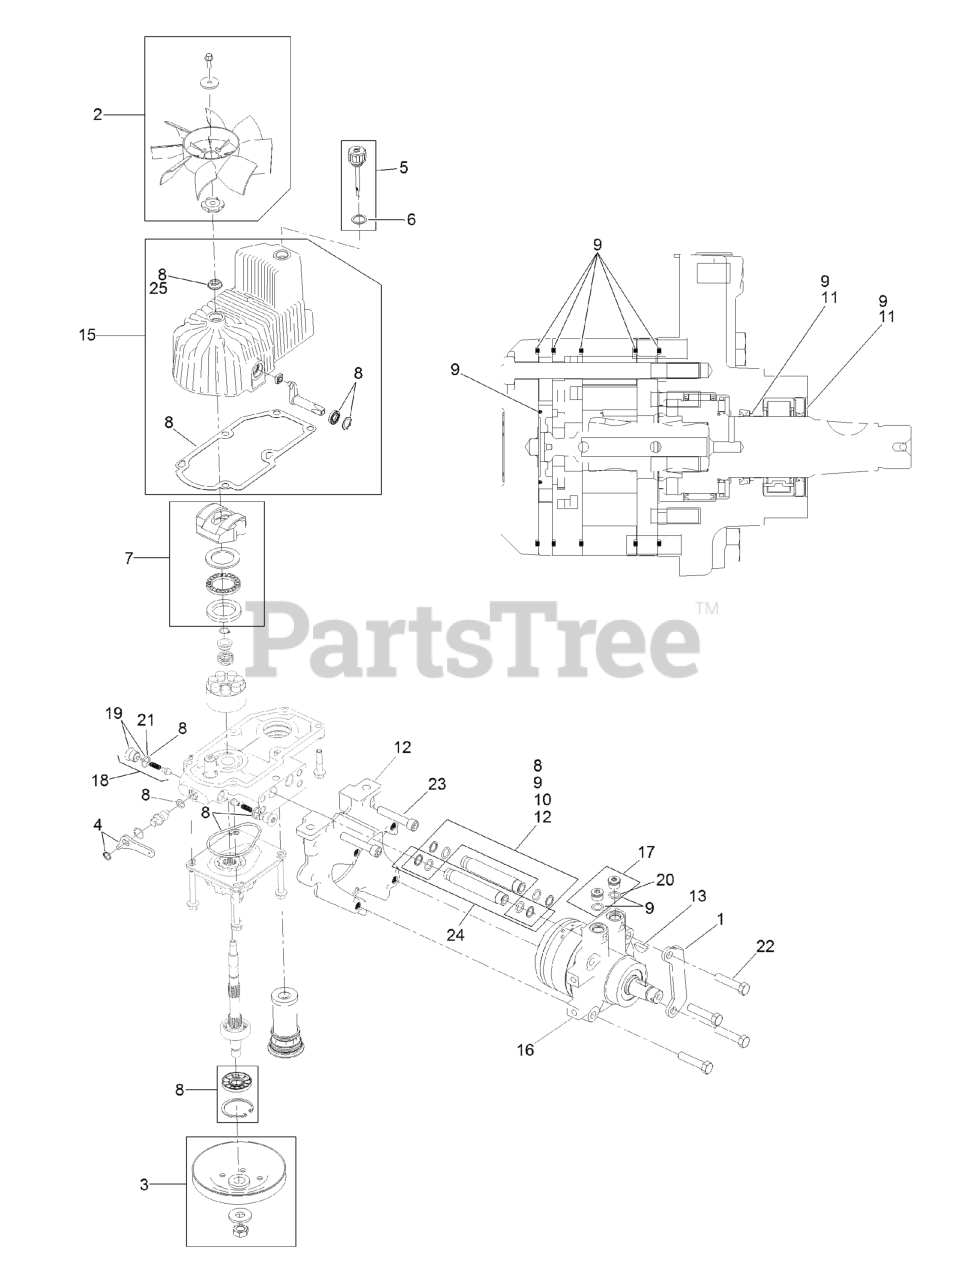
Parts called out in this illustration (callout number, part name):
1	MOUNT-SHOE, HORSE
2	FAN KIT
3	PULLEY KIT
4	HANDLE-BYPASS VALVE, HYDRO
5	DIPSTICK-HYDRO W/GASKET
6	GASKET-DIPSTICK, HYDRO
7	SWASH BLOCK KIT
8	PUMP SEAL KIT
9	MOTOR SEAL KIT
10	TUBE SEAL KIT
11	OUTPUT SHAFT SEAL KIT
12	NOSE CUP-UHT
13	KEY-WOODRUFF
15	HOUSING-HYDRO, RH
16	MOTOR-HYDRAULIC RH 240CC
17	MAGNETIC PLUGS SERVICE KIT
18	CHECK VALVE ASM
19	PLUG-CHECK (W/O-RING)
21	O-RING-CHECK VALVE
22	SCREW HH
23	SCREW-HSH
24	HYDRAULIC TUBE KIT
25	SEAL-FAN DRIVE
26	Kit, Pump Section 12Cc RH
27	KIT, ROTATING GRP 12CC RH
